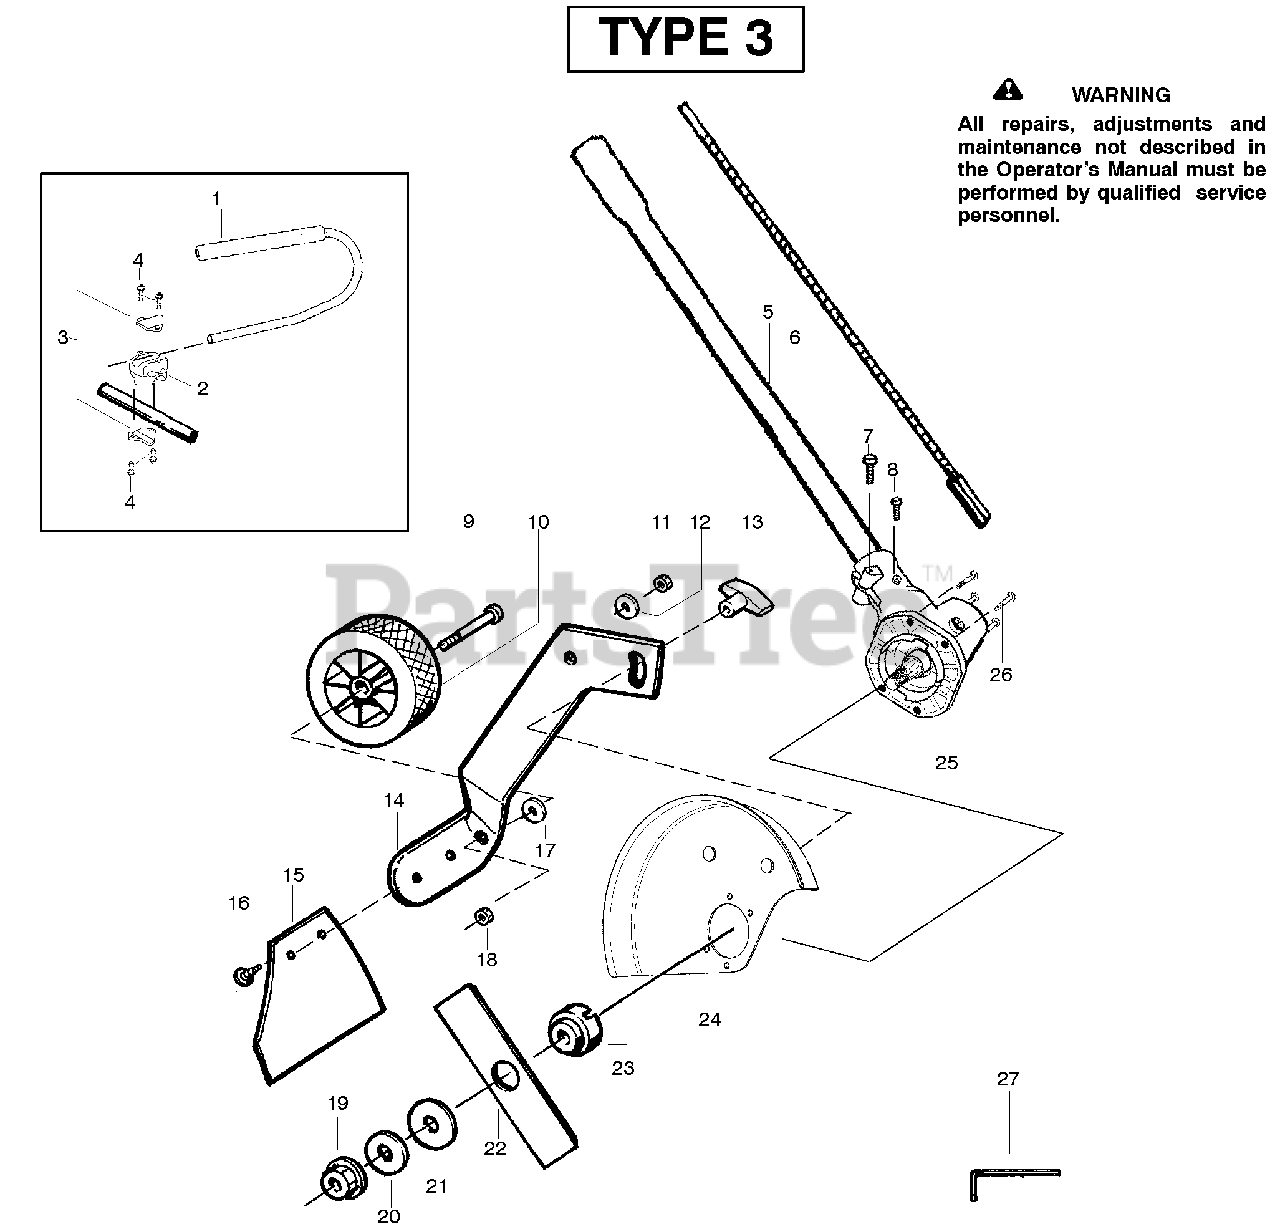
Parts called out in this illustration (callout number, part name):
1	Kit-Handlebar
2	Clamp-Handlebar ( 7/8" )
2	Clamp-Handlebar ( 1" )
3	Bracket-Clamp
5	Assy.-Driveshaft
6	Flexshaft-Split boom
8	Screw-Alignment
9	Bolt-Shoulder Axle
10	Wheel-4" (rubber)
14	Bracket-Adj. Wheel
15	Kit-Mud Flap
16	Fastener-Mud Flap
19	Nut-Flange (L.H.)
20	Washer-Belleville
22	Accy-7.5" Blade
24	Kit-Edger Guard
27	Wrench-Hex (5/32")
